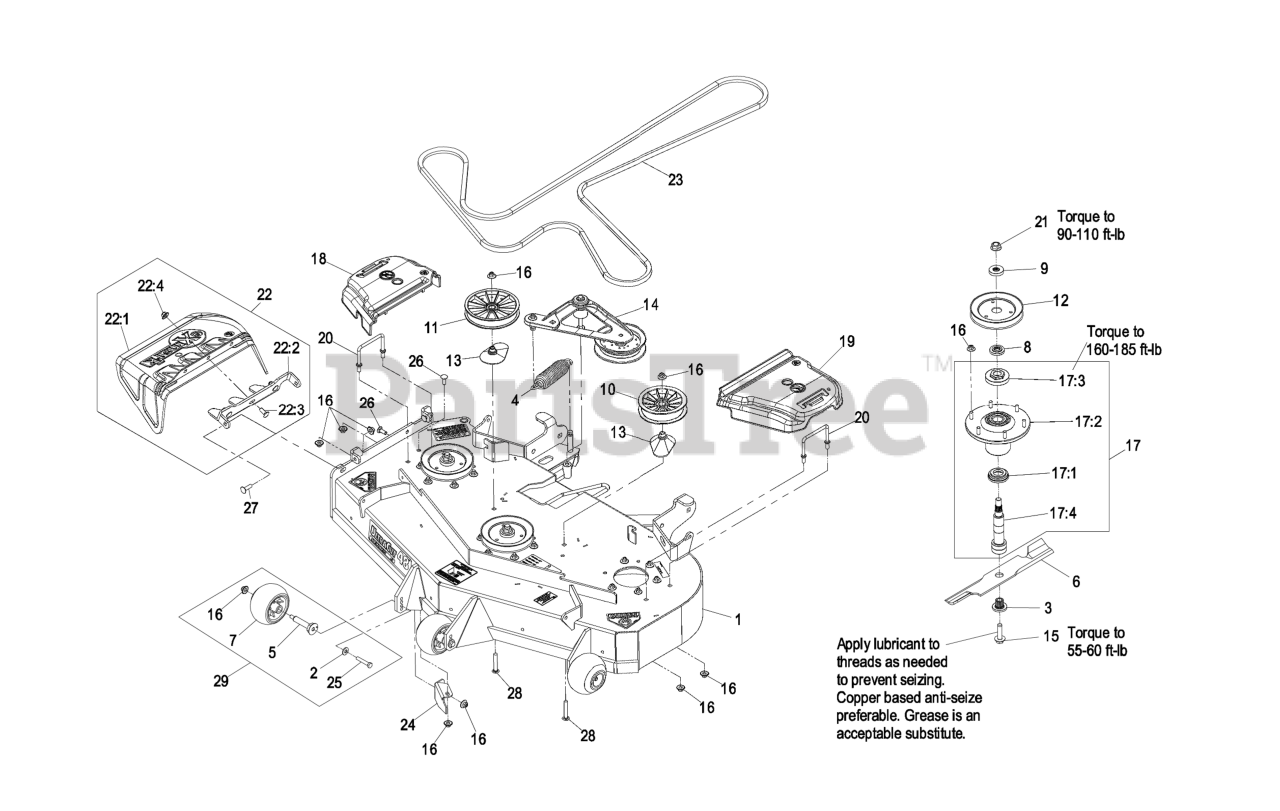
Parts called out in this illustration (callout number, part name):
1	ASM,DECK W/DECALS 48
2	WASHER-BELLEVILLE
3	BUSHING,SPLINED
7	ROLLER-SCALP, ANTI
8	SPACER,SPLINED STEPPED
9	SPACER,SPLINED
10	PULLEY,IDLER 5"
11	PULLEY,IDLER 6"
12	SHEAVE,BLADE DRIVE 5.90
13	SPACER-PULLEY
15	SCREW,SEMS 1/2-20 X 2.19
16	Nut-Nyloc 3/8-16 Flg
17	ASM,SPINDLE HOUSING
17:1	GUARD,BOTTOM
17:2	ASM,CUTTER HOUSING
17:3	NUT, SPINDLE 7/8-14
17:4	SPINDLE,DOUBLE SPLINE
18	COVER-BELT, RH
19	COVER-BELT, LH
20	WIREFORM-COVER
21	NUT-FLANGE, CENTERLOCK
22	ASM,DISCHARGE CHUTE
22:1	CHUTE,DISCHARGE
22:2	BRACKET,DISCHARGE CHUTE
22:3	SCREW-CARR
22:4	Nut-Nyloc 3/8-16 Flg
23	BELT
24	BAFFLE,DISCHARGE
25	SCREW-HH
26	SCREW-CARR
27	Bolt-Carriage 3/8-16 X 1 1/4
28	SCREW-CARR
30	Asm, Deck Complete 486
